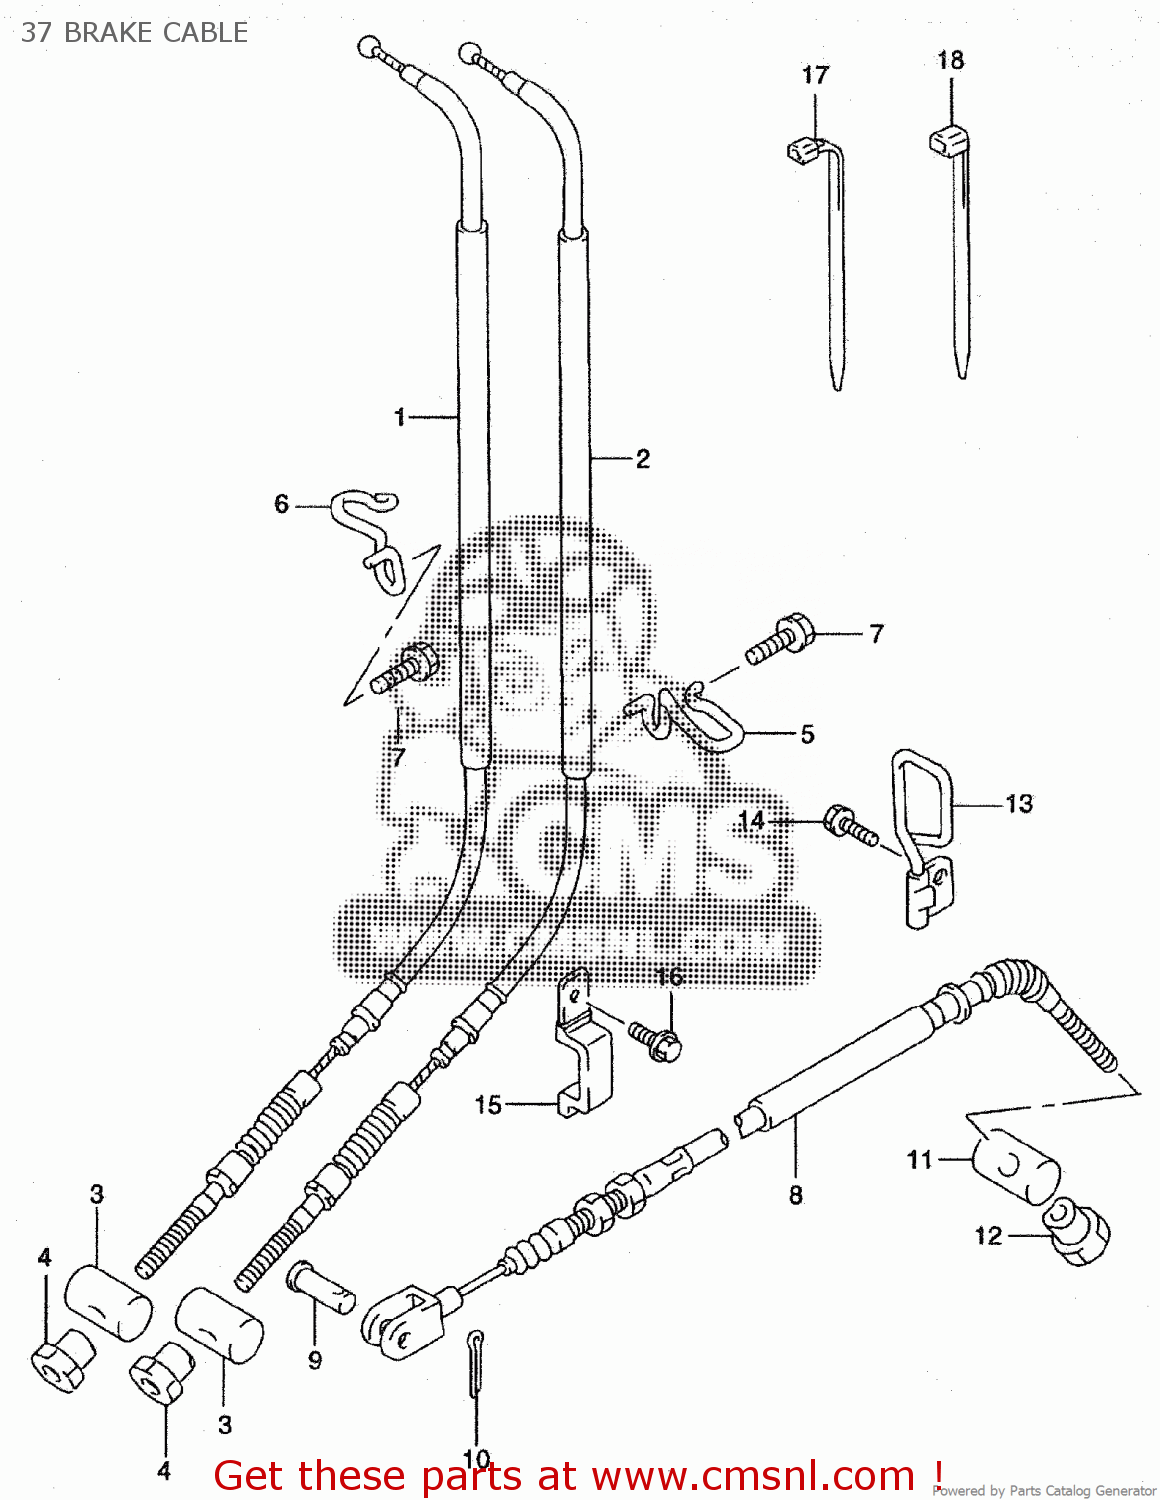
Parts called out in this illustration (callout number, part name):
1	REMKABEL
2	REMKABEL
3	PIN(13X18)
4	NUT
7	BOLT
9	PIN(L:17.5)
10	PIN
11	PIN(13X18)
12	NUT
14	BOLT
15	CLAMP
16	BOLT
17	CLAMP(L:165)
18	CLAMP(L:235)
